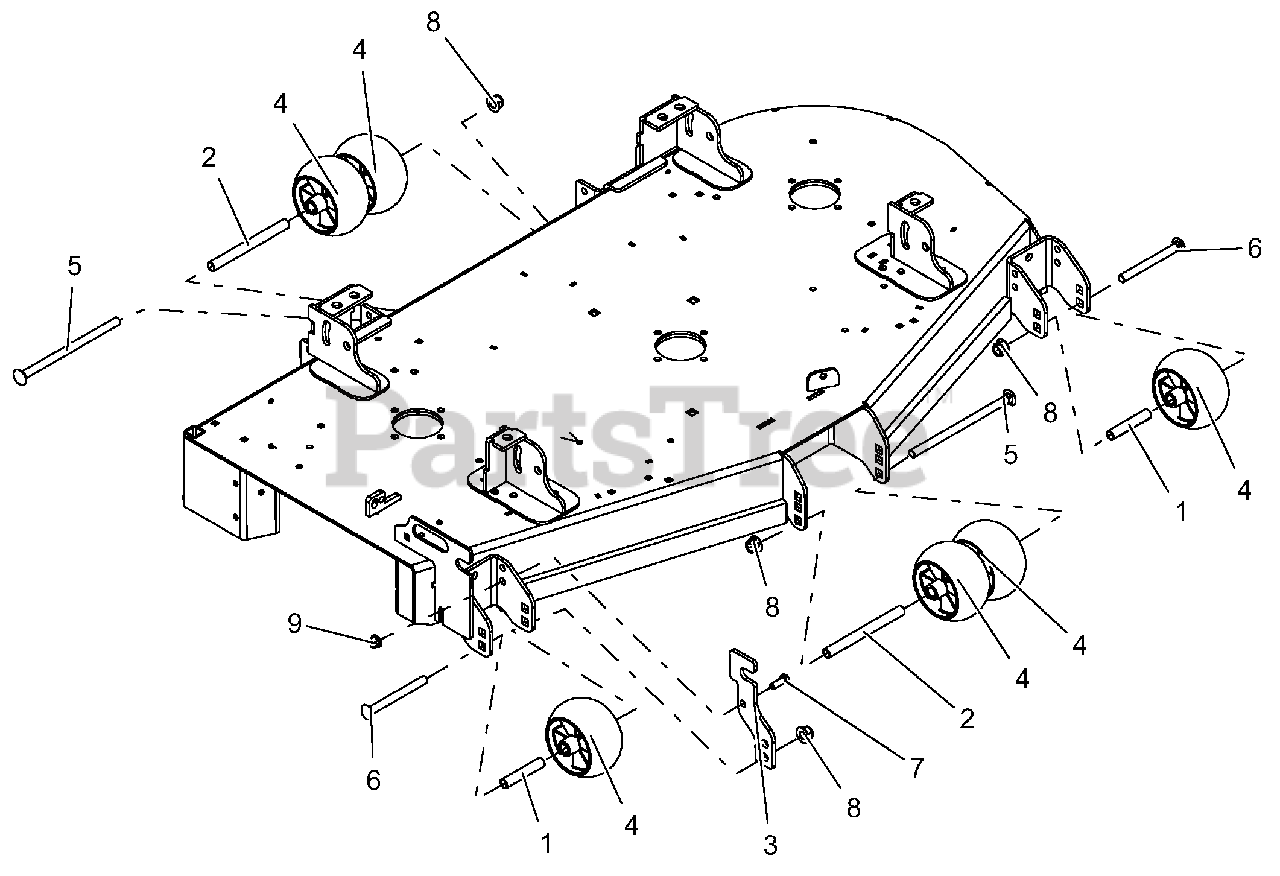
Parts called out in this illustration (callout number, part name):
1	SPACER, .510X.625X3.35
2	SPACER, .510 X .625 X 6.50
3	CHUTE STORAGE BRACKET-RED
4	ANTI-SCALP WHEEL - 5X3 CTR
5	BLT-RDHDSQNK .50-13X8.50 Y
6	BLT-RDHDSQNK .50-13X5.00 G5 YWZC
7	BLT-HEX .38-16X1.00 GR5 YWZC
8	NUT-LK-NYL-FLG .50-13 YWZC
9	NUT-LK-NYL-FLG .38-16 YWZC
